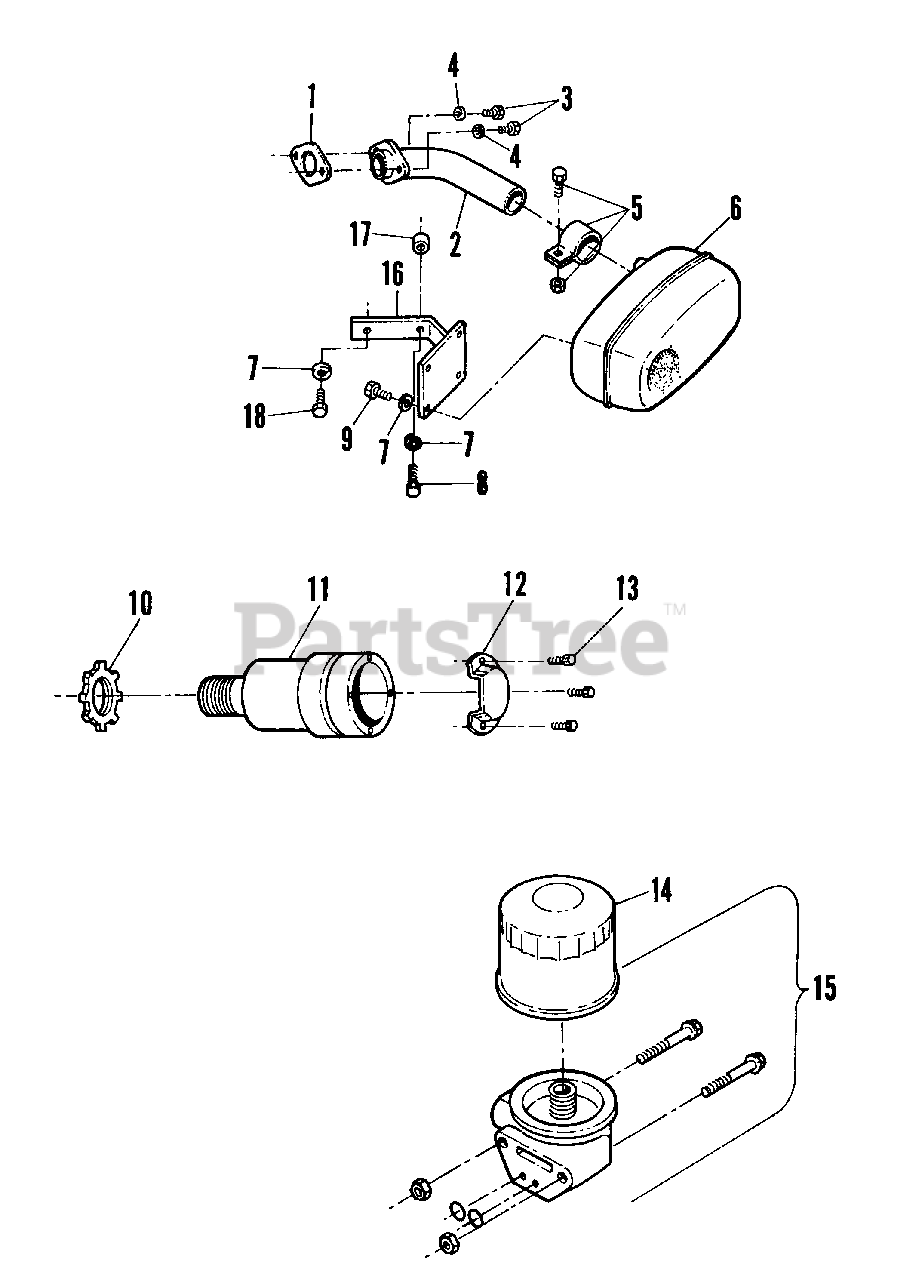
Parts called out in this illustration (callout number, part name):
1	GASKET, Exhaust
2	TUBE, Exhaust Assembly
3	SCREW, Hex Head Cap 5/16" - 18 x 3/4"
4	WASHER, Lock 5/16"
5	CLAMP, Muffler w/Bolt & Nut
6	MUFFLER, Super Lo-Tone (12 hp Briggs)
7	WASHER, Lock 1/4"
8	SCREW, Hex Head Cap 1/4" x 20 x 3/4"
9	SCREW, Hex Head Cap 1/4" x 20 x 5/8"
10	RING, Locking
11	MUFFLER, Round Lo-Tone (8 hp Briggs)
12	DEFLECTOR, Side Out
13	SCREW, Muffler Deflector
14	OIL FILTER (12.5 hp Kawasaki)
15	OIL FILTER KIT (12.5 hp Kawasaki)
16	BRACKET, Muffler Mount (12 hp Briggs)
17	SPACER, Muffler Bracket
18	SCREW, Hex Head Cap 1/4 - 20 x 1
